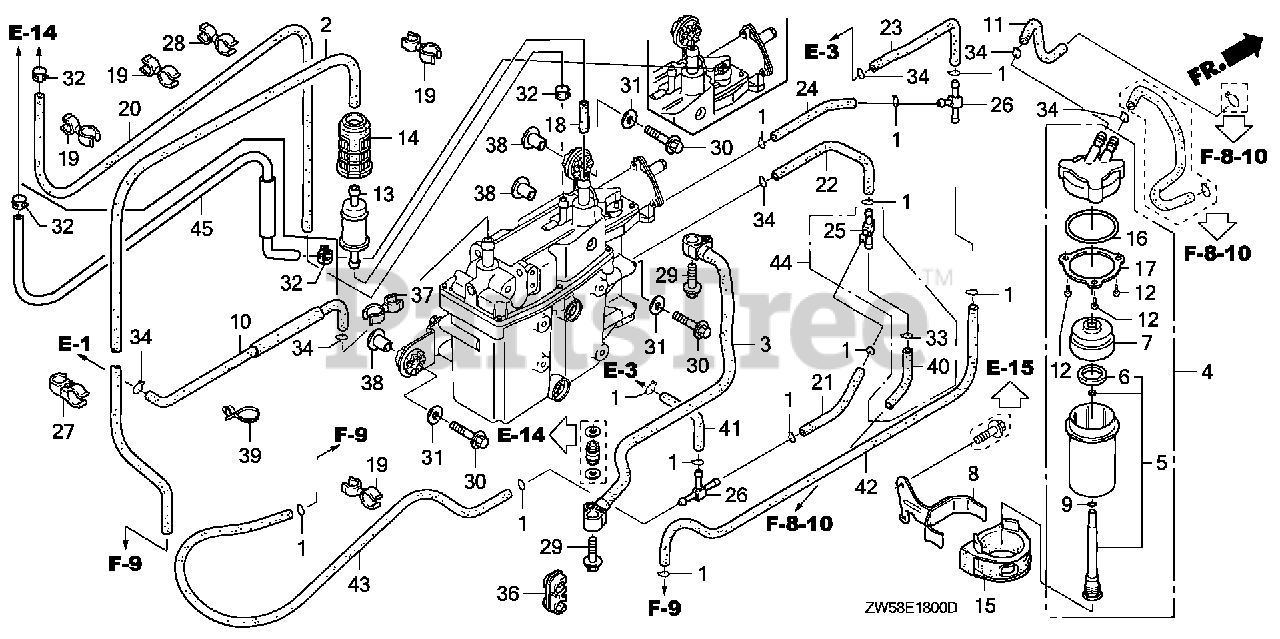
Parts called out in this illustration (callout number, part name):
1	CLIP, TUBE
2	TUBE B, AIR VENT
3	HOSE, FUEL
4	SEPARATOR ASSY., WATER
5	CUP, WATER SEPARATOR
7	BUFFER, PLATE
8	STAY, WATER SEPARATOR
10	TUBE, FUEL (D)
11	TUBE E, FUEL
12	SCREW, PAN (5X12)
13	FILTER, FUEL PUMP
14	SUSPENSION, STRAINER
15	SUSPENSION, STRAINER
18	TUBE B, FUEL
19	CLAMP, HOSE
20	HOSE, PRESSURE REGULATOR RETURN
21	TUBE A, WATER
22	TUBE B, WATER
23	TUBE C, WATER
24	TUBE D, WATER
25	T-JOINT
26	JOINT, THREE WAY
27	CLIP, SENSOR HOSE
29	BOLT, FLANGE (6X25)
30	BOLT, FLANGE (8X35)
31	WASHER, PLAIN (8MM)
32	CLAMP, TUBE (D10.7)
33	CLIP, TUBE (B8)
33	CLIP, TUBE (B10)
34	CLIP, TUBE (B12)
36	CLAMP, FUEL TUBE
37	CLAMP (6MM-12MM)
38	COLLAR (8.5X14.5)
39	CLIP, TUBE (135MM) (BLACK)
40	TUBE, WATER CHECK
40	BULK HOSE, VACUUM (4.5X1000) (4.5X50)
41	BULK HOSE, VACUUM (7X3000) (7X100)
42	BULK HOSE, VACUUM (7X3000) (7X550)
43	BULK HOSE, VACUUM (7X3000) (7X690)
